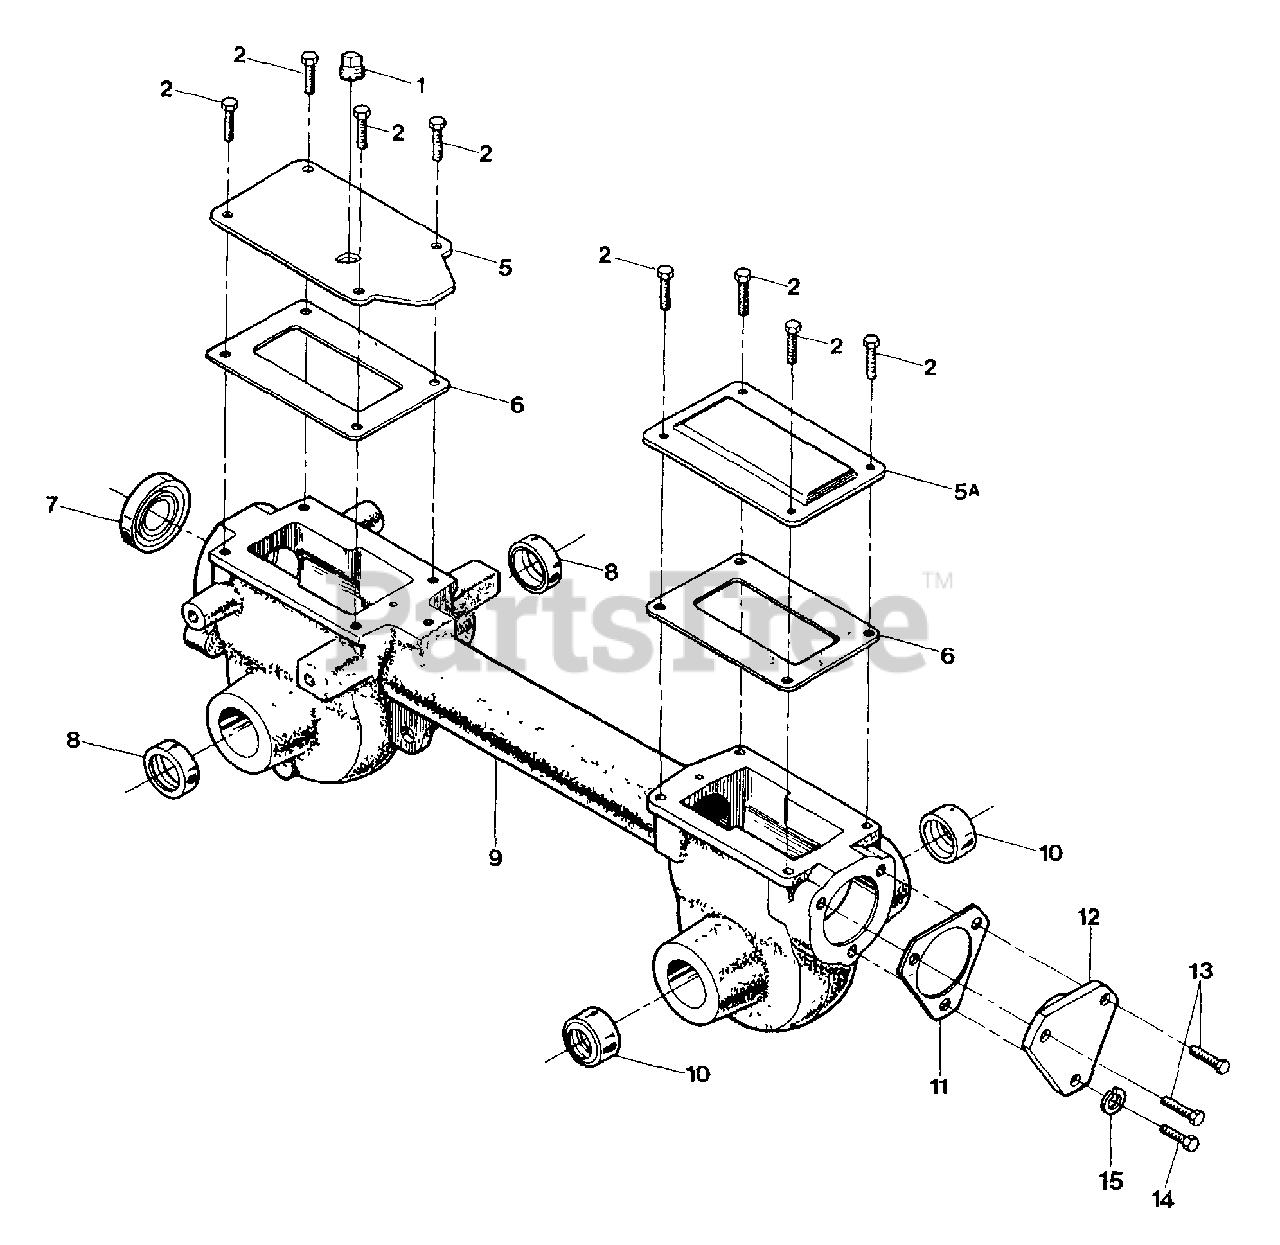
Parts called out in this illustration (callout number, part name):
1	Plug, Transmission Oil Fill
2	Hex Hd. Flange Screw, 5/16-18 x 5/8, Grade 5
5	Front Cover, Transmission
5A	Rear Cover, Transmission
6	Gasket, Housing Cover
7	Oil Seal, Drive Shaft
8	Oil Seal, Wheel Shaft
9	Transmission Housing Ass'y
10	Oil Seal, Tine Shaft
11	Bearing Cap Gasket, 010" thick
12	Rear Bearing Cap
13	Hex Hd Flange Screw, 5/16-18 x 1
14	Hex Hd Flange Screw, 5/16-18 x 3/4
15	Lock Washer, 5/16
